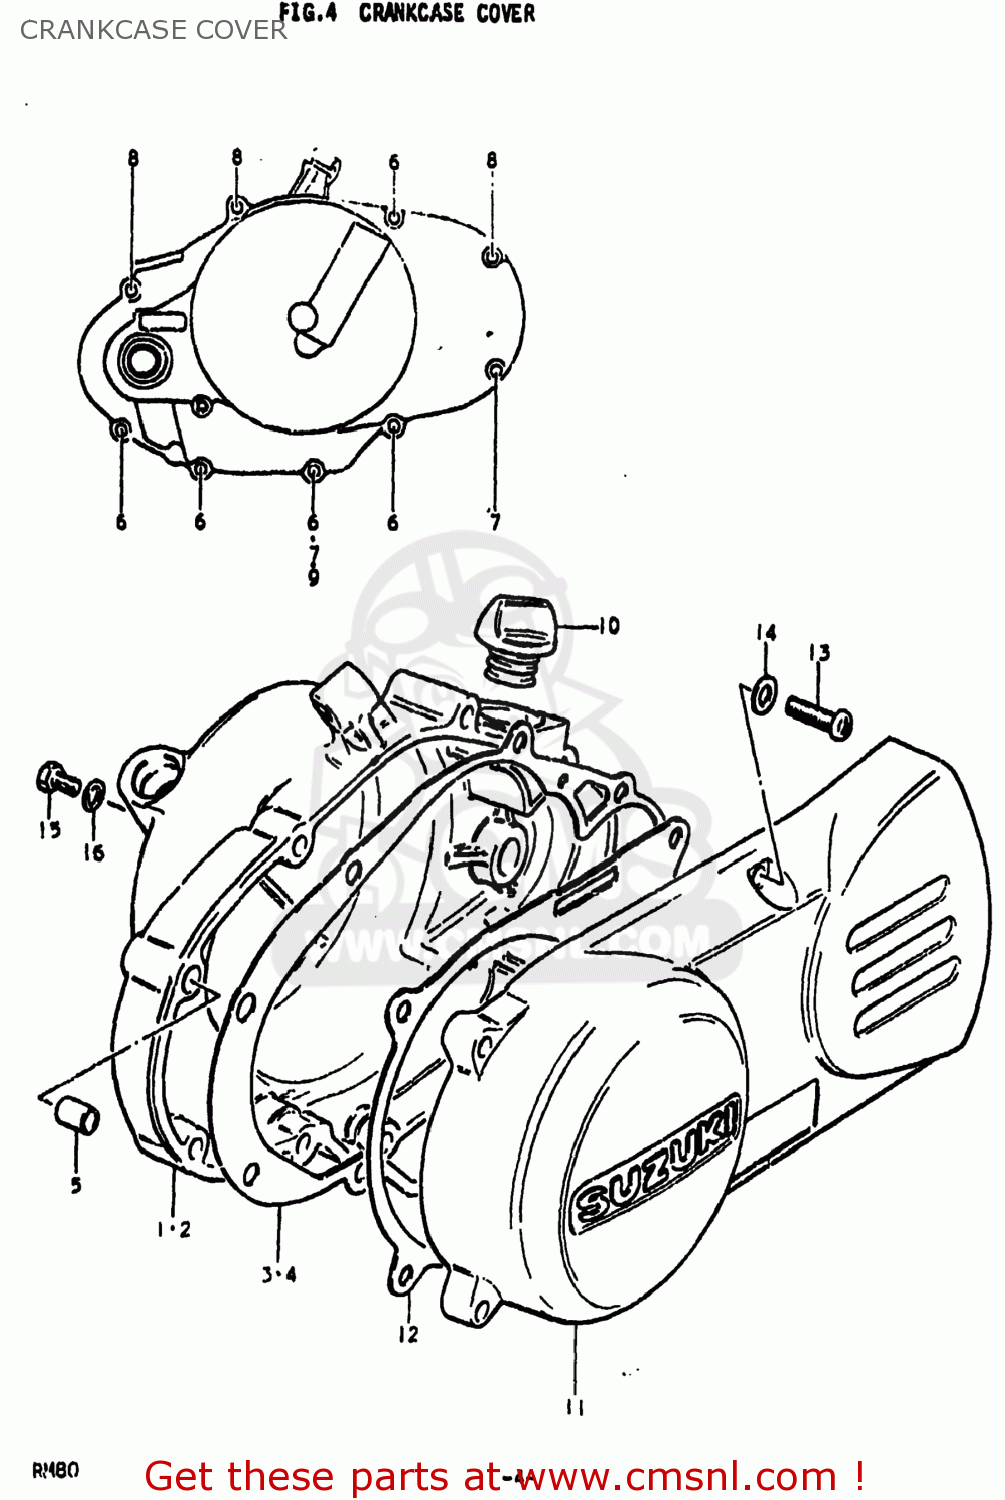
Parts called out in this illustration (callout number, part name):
1	COVER,CLUTCH
2	COVER,CLUTCH
3	GASKET,CLUTCH COVER (MCA)
4	GASKET,CLUTCH COVER (MCA)
5	PIN
6	SCREW
7	SCREW
8	SCREW
9	GASKET(6.2X11X1).2 (NAS)
10	PLUG
11	COVER,MAGNETO
12	GASKET,MAGNETO COVER (MCA)
13	SCREW
14	WASHER
15	SCREW(6X10)
16	GASKET(6.2X11X1) (NAS)
